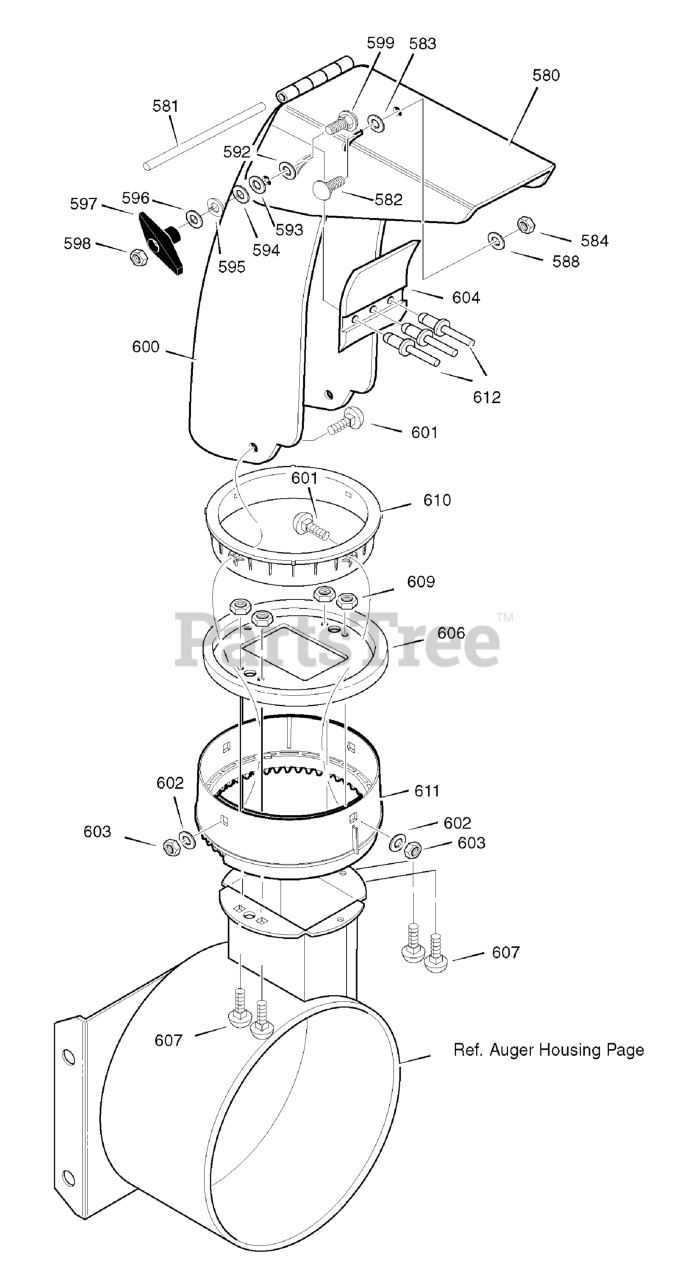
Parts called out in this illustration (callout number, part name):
580	UPPER CHUTE
582	BOLT, CARRIAGE 5/16-18 X .75
583	WASHER, PLASTIC
584	NUT, 5/16-18 REGHEX NYLOCK
588	WASHER, PLASTIC
592	WASHER, PLASTIC
593	WASHER, PLASTIC
594	WASHER, FLAT
595	WASHER, SPLIT
596	WASHER, FLAT
597	KNOB, T 3.00
598	NUT, 5/16-18 REGHEX
599	BOLT, 5/16-18 X 1.50
600	LOWER CHUTE
601	BOLT, 5/16-18 X 1.00
602	WASHER, FLAT
603	NUT, 5/16-18 HEXNYL
604	FLAP, CHUTE
606	CHUTE COLLAR
607	SCREW, 1/4-20 X .75
609	NUT, 1/4-20 HEX NYLOCK
610	RETAINER RING INNER
611	RETAINER RING OUTER
